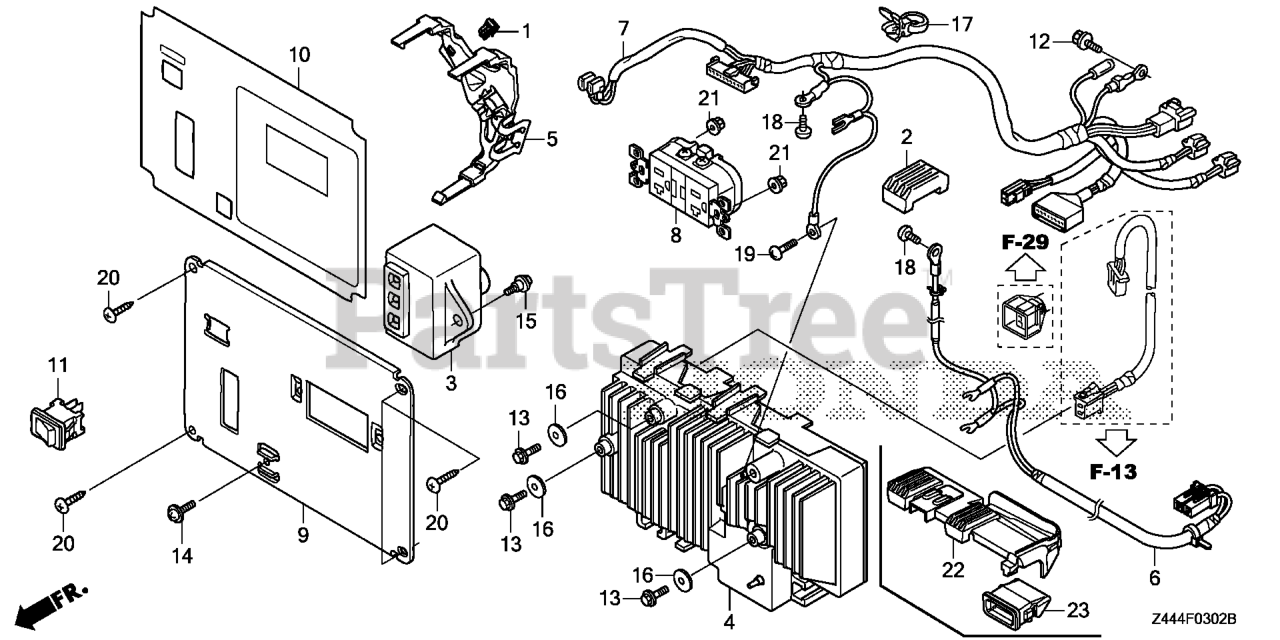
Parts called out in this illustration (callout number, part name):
1	CLIP, TUBE
2	RUBBER B, TANK MOUNTING
3	SPARK UNIT
4	INVERTER UNIT
5	BRACKET, INVERTER HARNESS
6	SUB-WIRE HARNESS ASSY.
7	WIRE HARNESS ASSY., CONTROL
8	RECEPTACLE (20A-125V) (GFCI)
8	RECEPTACLE
9	PANEL, CONTROL (EB-A)
10	MARK, CONTROL PANEL
11	SWITCH, AUTO-THROTTLE (OTAX)
12	BOLT, FLANGE (5X10)
13	BOLT, FLANGE (5X12)
14	SCREW, PAN (5X12) (GROUND CABLE)
15	SCREW, PAN (5X13)
16	WASHER, PLAIN (20MM)
17	BAND (100MM) (BLACK)
18	SCREW, PAN (5X8)
19	SCREW, PAN (5X10)
20	SCREW, TAPPING (5X16) (PO)
21	NUT, FLANGE (4MM)
22	RUBBER B, TANK MOUNTING
23	COVER, CONNECTOR
